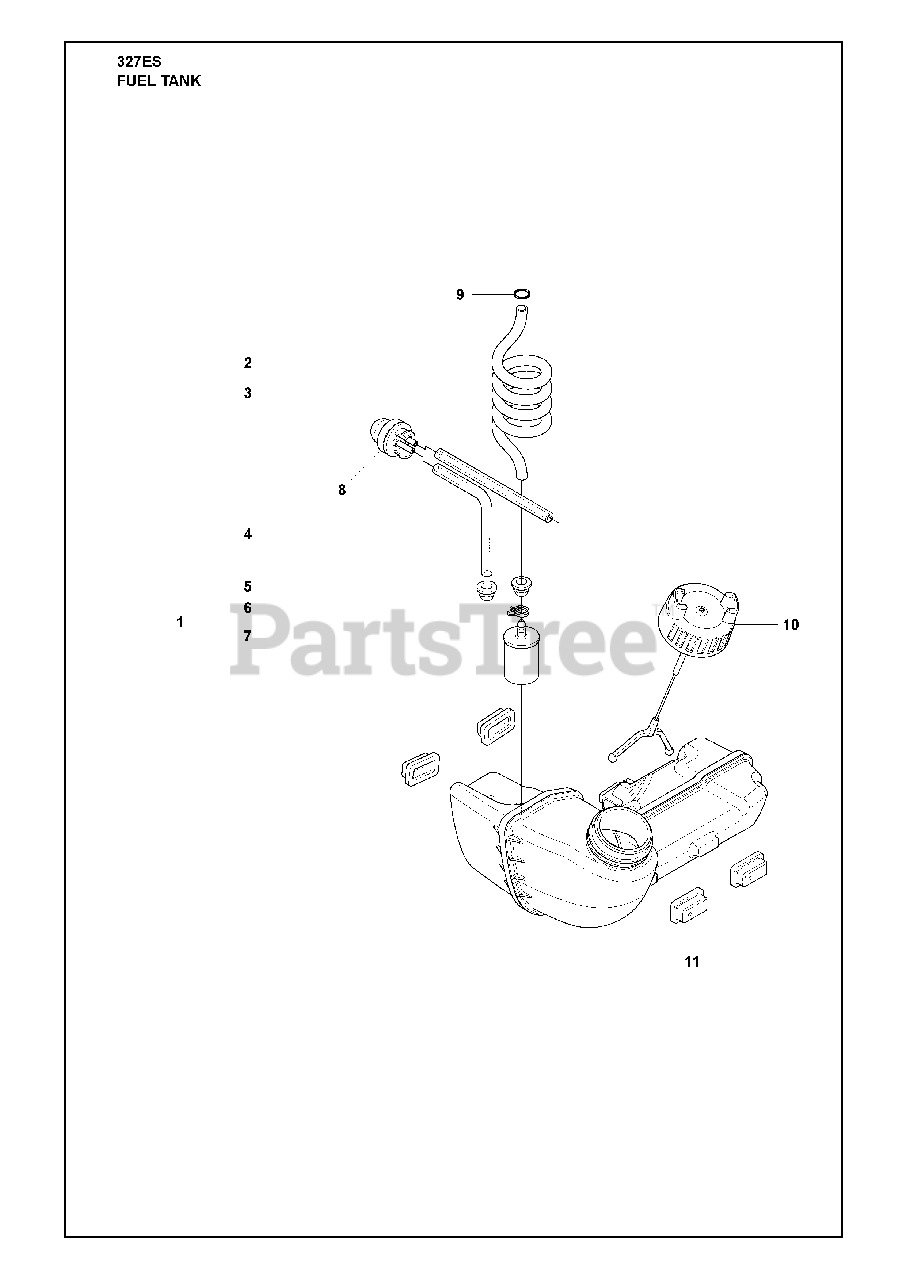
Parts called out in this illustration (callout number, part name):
1	RP FUEL TANK ASSY
2	FUEL HOSE
5	FUEL TANK BUSHING
6	HOSE CLAMP
7	FUEL FILTER
8	AIR PURGE BUBBLE
10	TANK CAP
